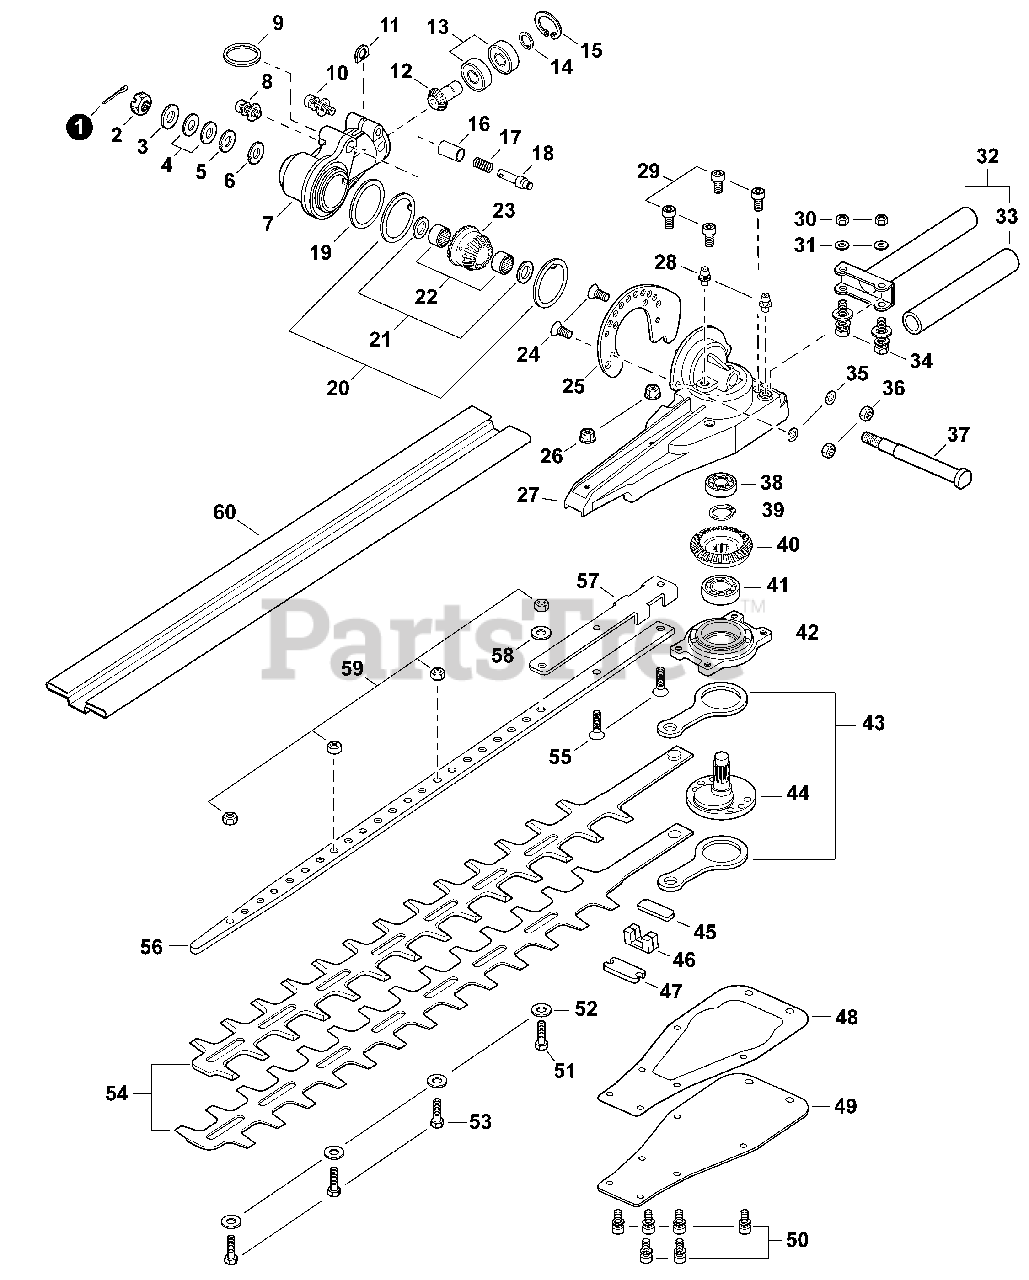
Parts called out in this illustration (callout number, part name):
1	PIN, COTTER 6×18
3	WASHER 8
4	WASHER, CONICAL
6	GASKET, GEAR CASE
7	CASE, GEAR
8	SCREW 5×12
9	RING, RETAINING
10	BOLT 5×25
12	GEAR, BEVEL
13	BEARING, BALL 6900
14	RING, SNAP
15	RING, SNAP Ø22
16	COLLAR 8
17	SPRING, COMPRESSION
18	LINCHPIN
19	O-RING 32
21	WASHER 10
22	BEARING, NEEDLE 10
23	GEAR, BEVEL
24	SCREW 4×12
25	BRACKET, ADJUSTOR
26	NUT, FLANGE M5
27	CASE, GEAR - CUTTER
28	FITTING, GREASE
29	BOLT 5×8
30	NUT, LOCK M5
31	WASHER, FLAT 5.5×10×0.8
32	ADJUSTOR ASSY, HANDLE
33	GRIP, HANDLE
34	BOLT 5×28
35	WASHER, SPRING 4 MM
36	NUT, LOCK 4
37	SHAFT, GEAR
38	BEARING, BALL 6900
39	RING, SNAP 11
40	GEAR, BEVEL
41	BEARING, BALL 6001
42	HOLDER, BEARING
43	ROD, CONNECTING
45	GUIDE, BLADE
47	GUIDE, BLADE
48	GASKET, GEAR CASE
49	COVER, GEAR CASE
50	BOLT 4×12
51	BOLT, CUTTER
52	WASHER 6.5×15.5×0.6
53	BOLT 6×18
55	SCREW 5×20
56	SUPPORT, BLADE
57	GUIDE, BLADE
58	WASHER 6.5×15.5×0.6
60	SCABBARD
